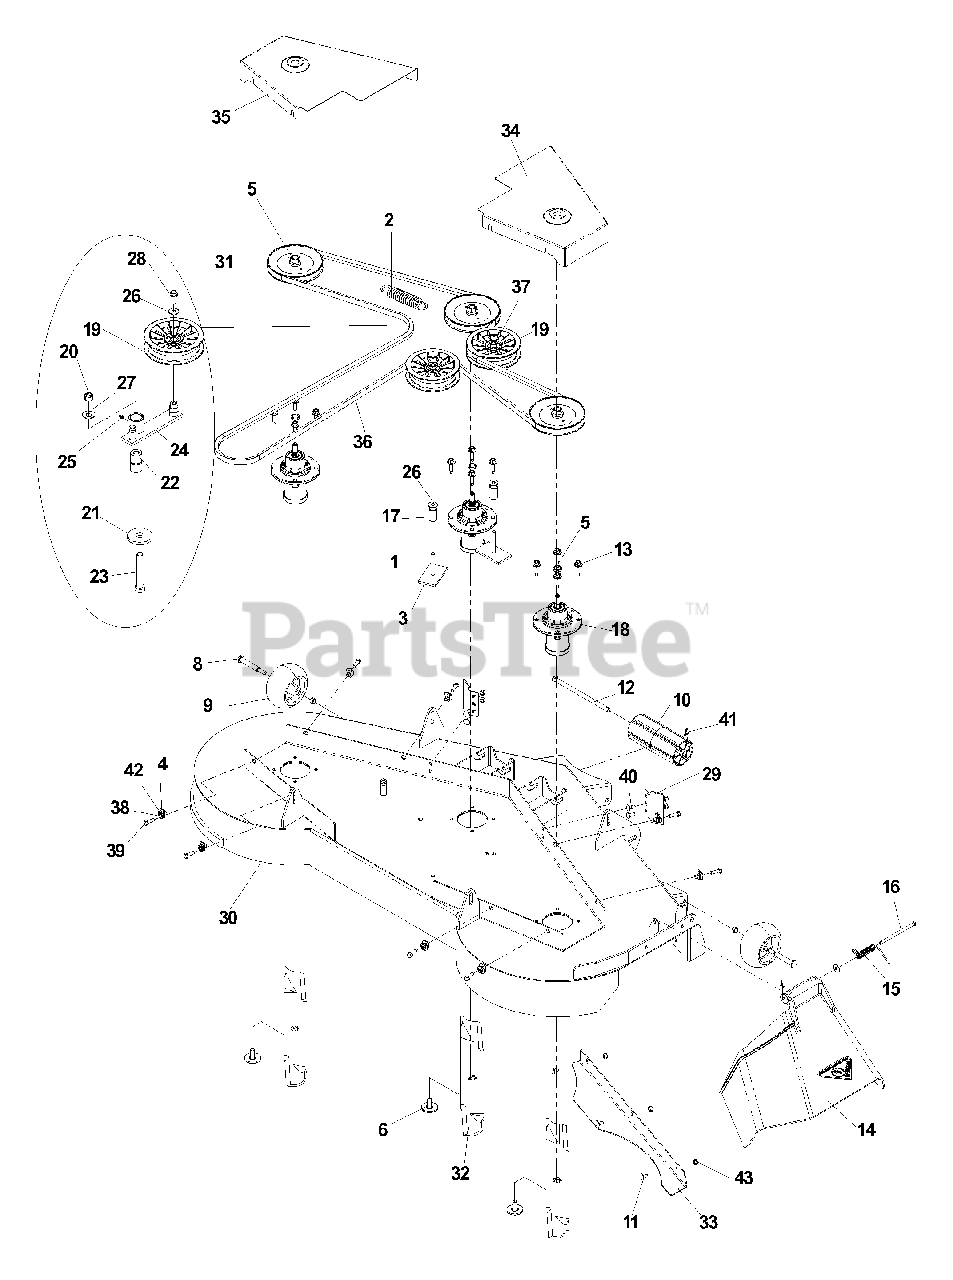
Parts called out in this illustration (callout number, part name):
1	HCS, 3/8-16 X 3, GR5
2	SPRING, EXTENSION
3	PAD
4	NUT, 5/16-18, RETAINER-U TYPE
5	WASHER, .675, SPACER
6	BOLT, 7/16, SPEC
7	NUT, 9/16, CENTERLOCK, GR5
8	SB, 1/2 X 2 5/8, SPEC
9	WHEEL, GAUGE
10	ROLLER, NOSE
11	RHSNB, 5/16-18 X 5/8, GR5
12	ROD, ROLLER, NOSE, NARROW
13	SCREW, 5/16-18 X 1 3/8, WASH HD, SPEC
14	DISCHARGE CHUTE
15	SPRING, TORSION
16	PIN-CLEVIS, 5/16 DIA. X 5.19
17	IDLER BUSHING
19	IDLER PULLEY, NYLON
20	NUT, 1/2-13, NYLOC
21	WASHER, .65 X 2 X .25, SUPPORT
22	BUSHING-PIVOT
23	HCS, 1/2-13 X 3 1/4, GR5
25	ZERK, STRAIGHT, 1/4-28
26	WASHER, 3/8
27	WASHER, .562 X 1.38 X 14
28	HCS, 3/8-16 X 1, GR5, WHIZLK
30	DECK W/DECALS
32	BLADE, 21"
33	CONFINEMENT PLATE
34	BELT SHIELD, RIGHT
35	BELT SHIELD, LEFT
37	NUT, 3/8-16, NYLOC
38	WASHER, 5/16
39	HCS, 5/16-18 X 1, GR5
40	RHSNB, 5/16-18 X 3/4, GR5
41	PIN COTTER, 1/8 X 3/4
42	WASHER, 5/16
43	NUT, 5/16-18, NYLOC
